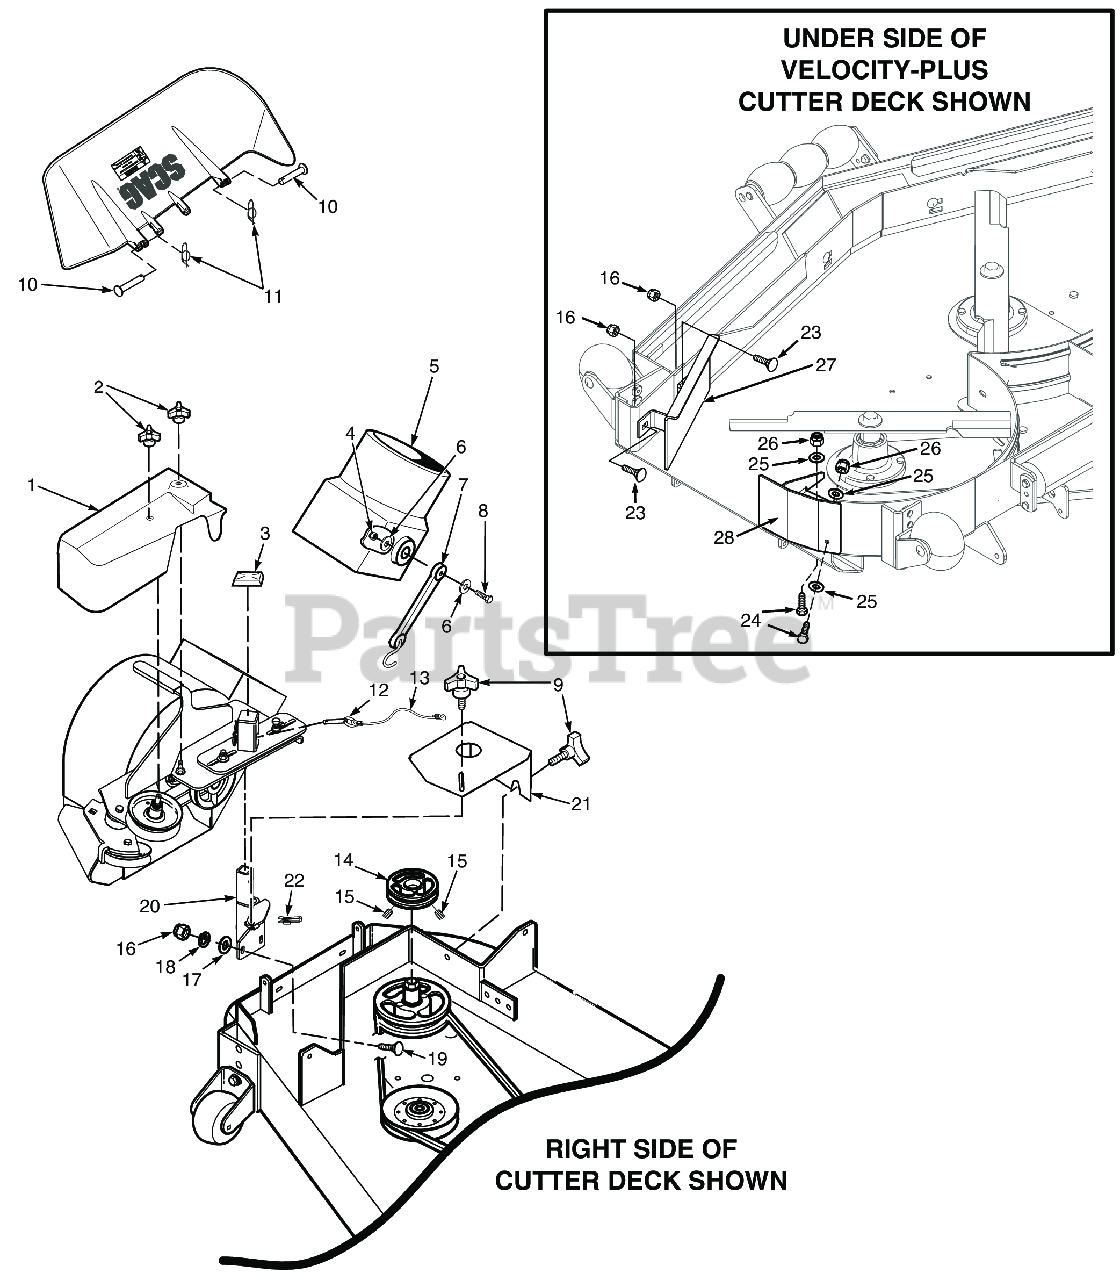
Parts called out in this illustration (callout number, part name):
1	Belt Cover, GC-STT - 61"
1	Belt Cover, (STT-52 & STTII-52)
2	Wing Nut, 3/8-16 (Small) Top side
3	Cap, Square Vinyl
4	HEX, NUT, ELASTIC STOP LOCK, 1/4-20
5	Adapter, Blower GC-STC,
6	Flatwasher, 1/4" (.312 x .750 x .065")
7	Rubber Strap 7-3/4"
8	SERR. FLG. HEX HEAD CAPSCREW, 5/16-18 X 3/4
9	Knob, w/stud 3/8-16 x 1-1/4"
10	Clevis Pin, 5/16 x 1-1/2"
11	Pin, Rue Cotter 5/16 Dia.
12	Pin, Ring 1/2 x 2-1/4"
13	Lanyard, Deck Height Pin
14	Pulley, 5-1/2" Dia. - 1.125" Bore, (61")
14	Pulley, 4.0" Dia. - 1.125" Bore, (STT-52 & STTII-52)
15	Setscrew, Hex Socket Knurl Cup Pt. 5/16 - 18 (nylock)
16	HEX NUT, ELASTIC STOP LOCK, 3/8-16
16	Nut, Elastic Stop 1/2-13, (STT-52 & STTII-52)
17	Lockwasher, 3/8" Spring, Kawasaki FX / FS
18	Flatwasher, 3/8" Special (.391 x .938 x .105)
19	SHORT SQ. NECK CARRIAGE BOLT, 3/8-16 X 1-1/4"
19	Bolt, Hex Head 1/2-13 x 1-1/2", (STT-52 & STTII-52)
20	Mounting Post Weldment, Blower, (61")
20	Mounting Post Weldment, Blower, (STT-52 & STTII-52)
21	Belt Cover Assembly, GC-STT-61V w/Cap
21	Belt Cover, (STT-52 & STTII-52)
22	U-Nut, 3/8-16 (short)
23	Carriage Bolt, 3/8-16 x 1.0"
24	Bolt, Heax Head 5/16-18 x 1" (48V / 52V)
25	Flatwasher, 5/16-.375 x .875 x .083 (35BV & 37BV-EFI)
26	HEX NUT, ELASTIC STOP LOCK, 5/16-18
27	Baffle Weldment - 61" Deck
27	Baffle Weldment, 52V Deck
28	Baffle, Turbo - 61" Deck
28	Baffle, Turbo 52" Deck
